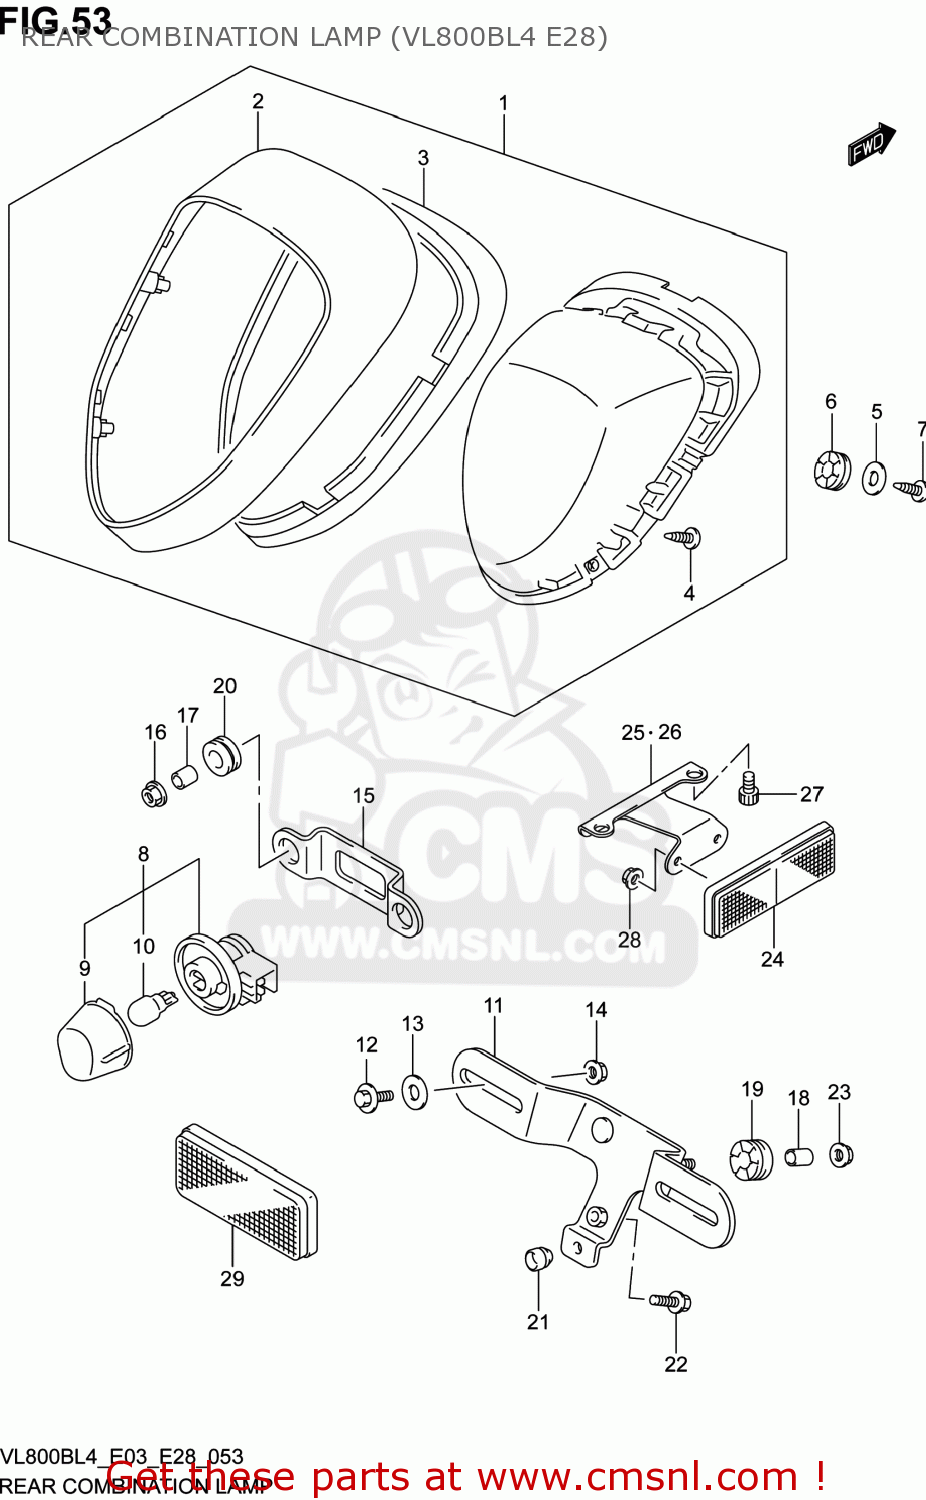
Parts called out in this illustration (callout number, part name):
1	LAMP ASSY,REAR COMB
2	COVER
3	RUBBER
4	SCREW(3X12)
5	WASHER(5.5X20X1.2)
6	CUSHION,RR COMBINATION
7	SCREW
8	LAMP ASSY,LICENSE
9	LENS
10	BULB(12V5W)
11	BRACKET,LICENSE PLATE
12	BOLT(6X16)
13	WASHER(6.5X20X1.2)
14	NUT
15	BRACKET,LICENSE LAMP
16	NUT
17	SPACER(5.5X9.5X11.5)
18	SPACER(6.5X10X12)
19	CUSHION
20	CUSHION
21	CUSHION
22	BOLT
23	NUT
24	REFLECTOR ASSY,RR
25	BRACKET,RR SIDE RR,R
26	BRACKET,RR SIDE RR,L
27	BOLT
28	NUT
29	REFLECTOR ASSY,RR
